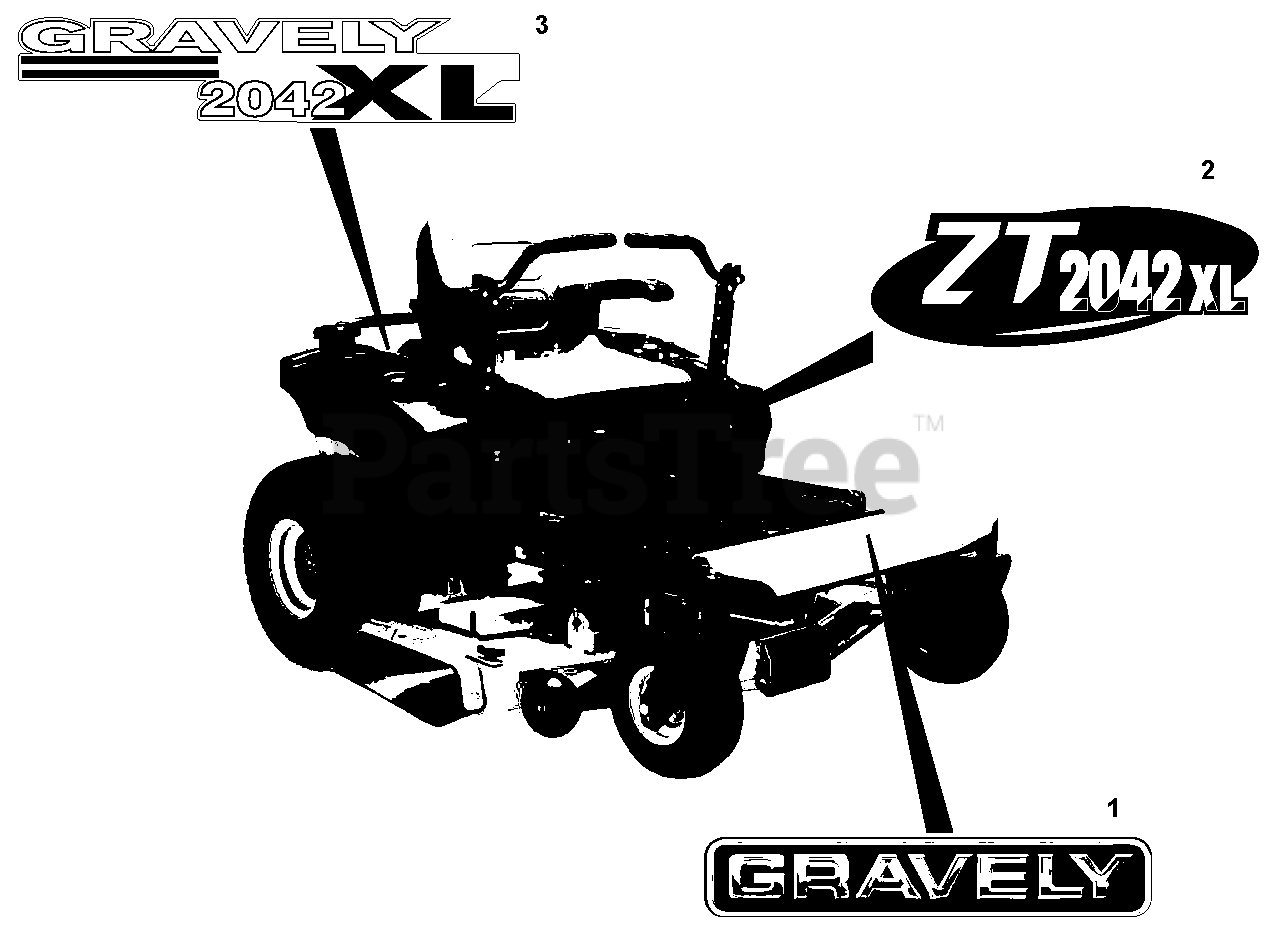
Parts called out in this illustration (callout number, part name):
1	Decal, Gravely Logo
2	Decal, 2042 ZT XL
3	Decal, 2042 ZT XL Hood
